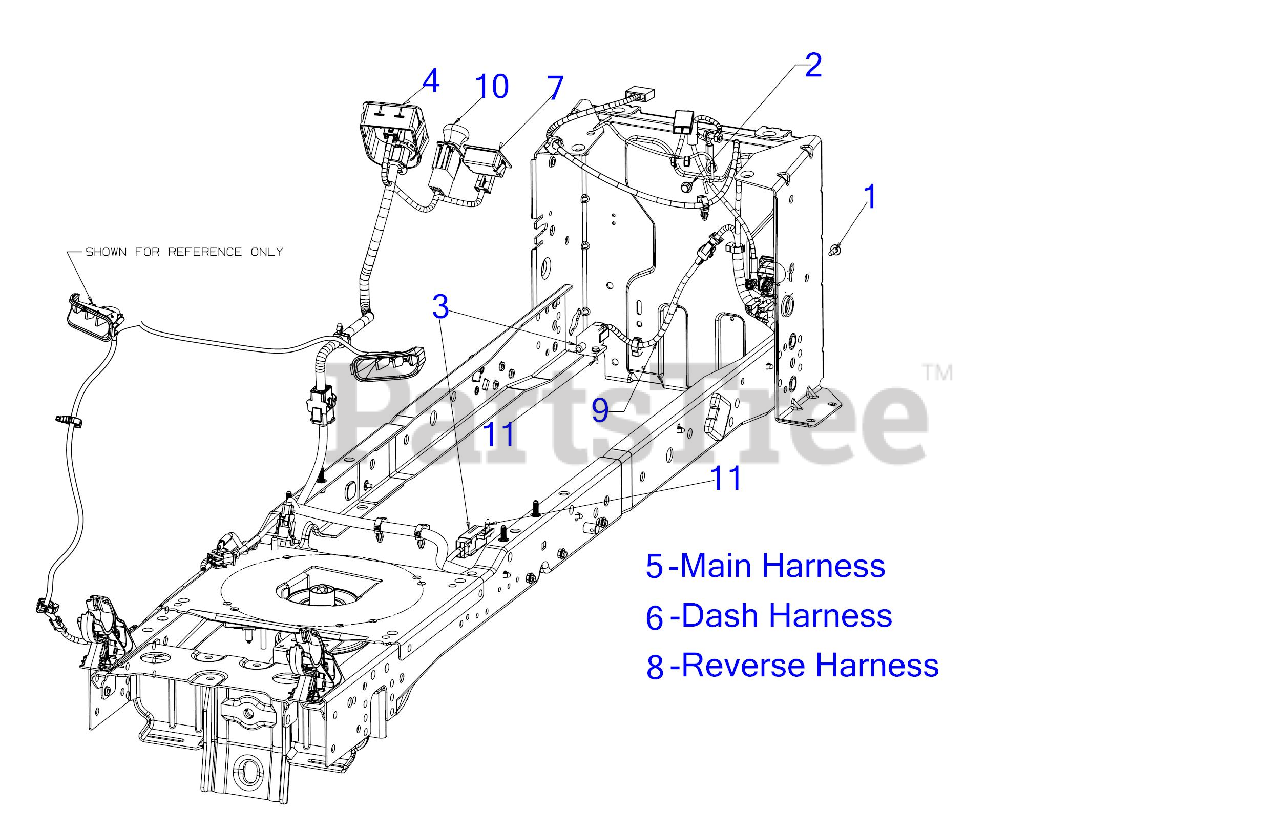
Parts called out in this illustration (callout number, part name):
1	SCREW M6-1 x .625
2	SCREW 1/4-20X.625
3	INTERLOCK SWITCH (NO/NC)
4	IGNITION SWITCH MODULE
5	MAIN HARNESS
5	SOLENOID
6	DASH HARNESS
7	HOUR/SVC METER
7	Cub Cadet HOUR METER KIT
7	Troy-Bilt HOUR METER KIT
8	REVERSE HARNESS
9	CLUTCH HARNESS 11"
10	PTO SWITCH (YELLOW KNOB)
11	SHOULDER SCREW
